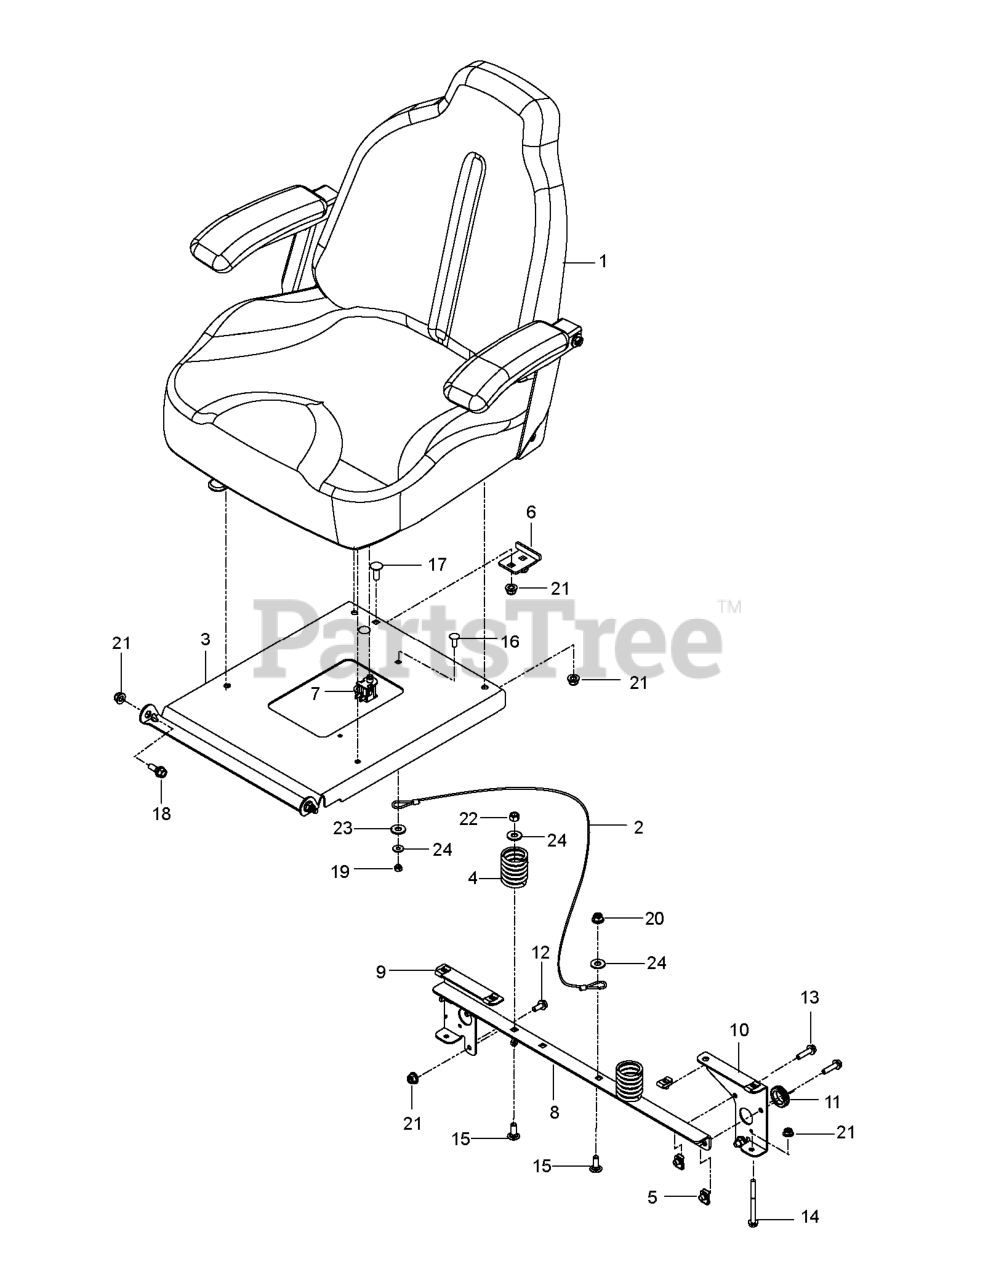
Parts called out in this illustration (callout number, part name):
1	SEAT.ASM.907.TRACK.W/O.BELT
2	SEAT LANYARD
3	SUPPORT.SEAT.ORANGE
4	SPRING.COMPRESSION.SEAT.BLACK
5	U-CLIP 5/16-18 NUT RETAINER
6	STOP, SEAT - BLACK
7	SEAT SWITCH
8	SUPPORT.SEAT. BLK
9	SUPPORT.RT.BLK
10	SUPPORT.LT.BLK
11	RUBBER GROMMET
12	HHFS 5/16-18 X 3/4
13	HHFS 5/16-18 X 1.25 TPBLT GD 5
14	BOLT.HEX.FLNG.5/16-18X3.75
15	BOLT D
16	BOLT
17	RHSNB 5/16-18 X 3/4 GR5 BLK ZN
18	SB 5/16-18 HEX HD GD5, BLK ZN
19	LOCKNUT.NYLOC.1/4-20
20	NUT 3/8-16 HEX FLG NYLOC ZD
21	5/16-18 NYLOC FLANGE NUT
22	NUT
23	WASHER PM
24	RP WASHER 3/8 FLAT
